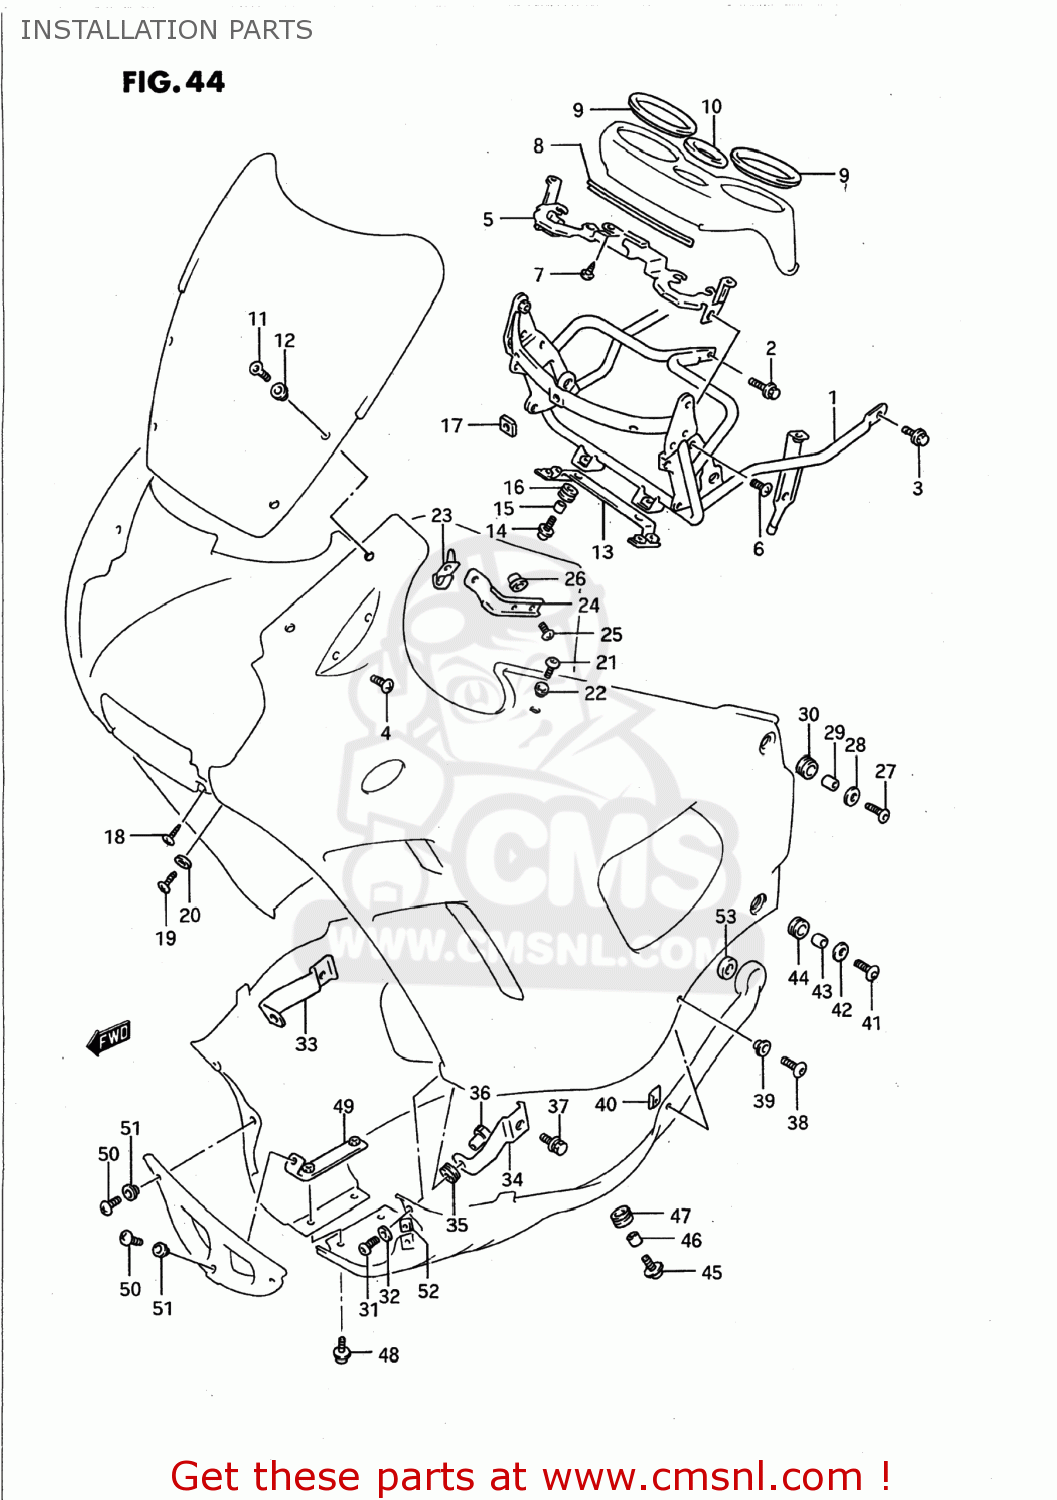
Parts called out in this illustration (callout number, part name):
1	BRACE,COWLING
2	BOLT
3	BOLT
4	SCREW 6X12
5	PLATE,METER FITING
6	SCREW 6X12
7	SCREW 5X8
8	MOLDING,METER COVER
9	CUSHION,SPEEDOMETER
10	CUSHION,FUEL METER
11	SCREW
12	WASHER(5.2X11X1)
13	PLATE,COWL CTR PANEL
14	SCREW(6X20)
15	SPACER (6,8X10X9.4)
16	CUSHION
17	CUSHION,SCREEN
18	SCREW
19	SCREW(6X25)
20	WASHER(6.5X18X1.5)
21	SCREW(6X16)
22	WASHER(6.3X16X1.5)
23	BRACKET,COWLING UPR,R
24	BRACKET,COWLING UPR,L
25	SCREW
26	NUT,COWLING SIDE BRKT
27	SCREW(6X25)
28	WASHER(6.5X18X1.5)
29	SPACER (6.1X9X9)
30	CUSHION
31	SCREW(6X30)
32	WASHER(6.5X18X1.5)
33	BRACKET,COWLING LWR,R
34	BRACKET,COWLING LWR,L
35	CUSHION
36	NUT,COWLING,FR
37	BOLT
38	SCREW(5X14)
39	WASHER(5.2X14X1.5)
40	NUT,HEADLAMP HOUSING,UPPER
41	SCREW(6X25)
42	WASHER(6.5X18X1.5)
43	SPACER(6.1X8X14.5)
44	CUSHION
45	SCREW(6X20)
46	SPACER (6.1X9X9)
47	CUSHION
48	SCREW
49	BRACKET,FR UNDER COWL
50	SCREW
51	WASHER(5.2X14X1.5)
52	NUT,HEADLAMP HOUSING,UPPER
53	CUSHION,UNDER COWLING RR
